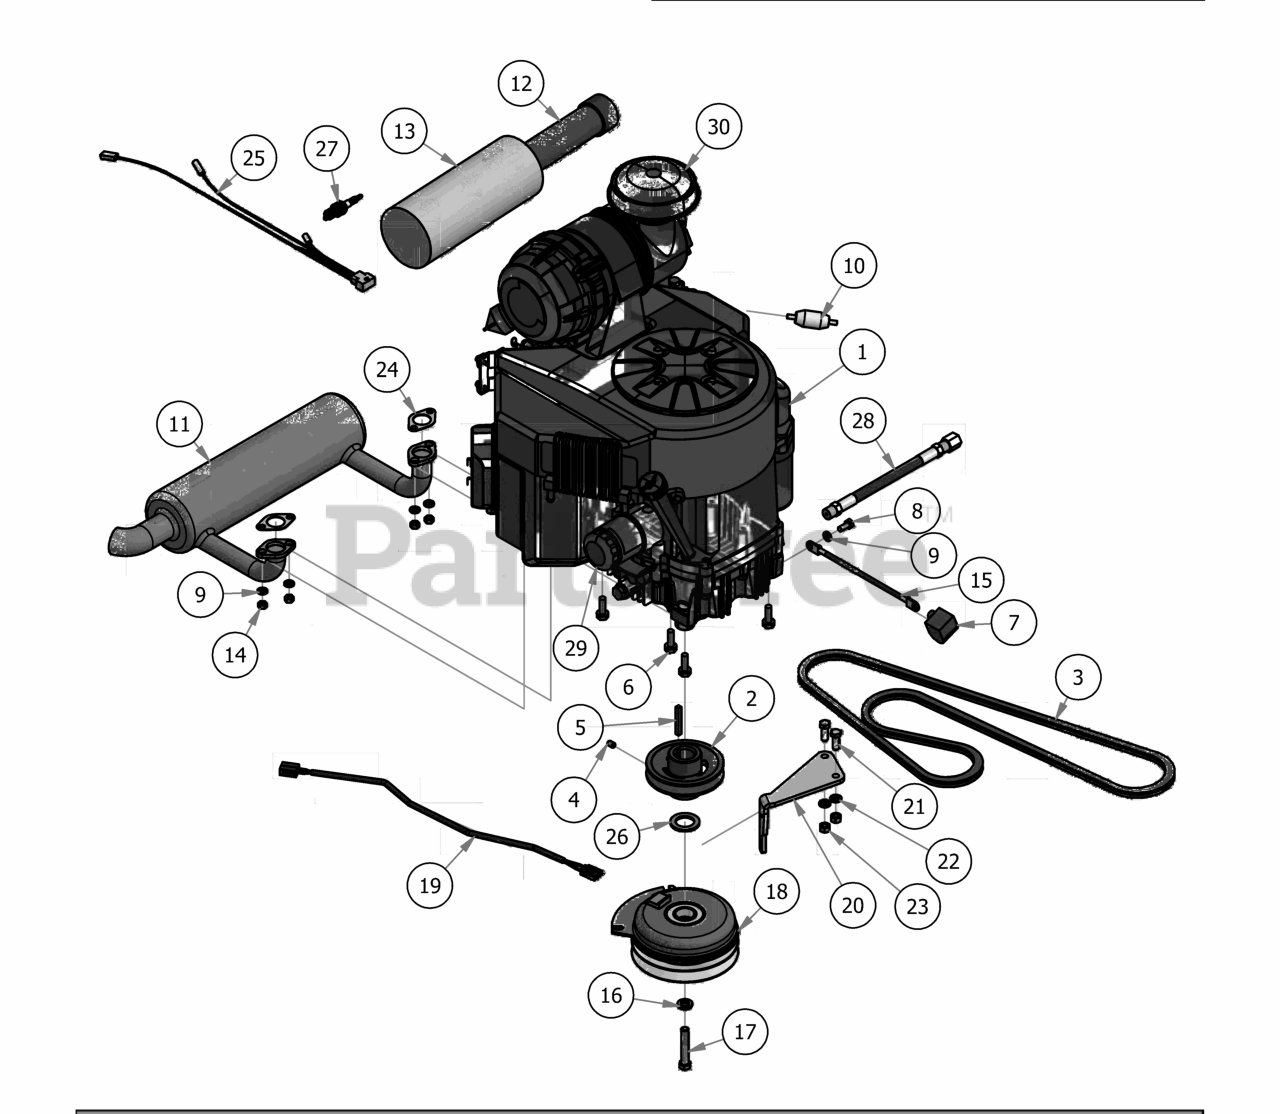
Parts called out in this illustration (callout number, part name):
1	FX-751-V Kawasaki
2	4 3/4 Motor Pulley
4	3/8" Set Screw
5	1/4 x 2 Square key Stock
6	3/8 x 1 1/8 bolt
7	Black Boot For Ground Cable
8	M8x1.20x20MM Hex head bolt
9	5/16" Lock Washer
10	Universal Inline Fuel Filter
11	Kawasaki Exhaust
12	Canister Air Filter- Inner
13	Canister Air Filter- Outer
14	M8-1.25 Zinc Nut
15	Ground Cable
16	7/16" Lock Washer
17	7/16" x 2 1/2" Hex Bolt
18	Clutch Assembly
19	Clutch Pigtail
20	PTO Engager Holder
21	3/8" x 1" Hex Bolt
22	3/8" Lock Washer
23	3/8" Hex Nut
24	Exhaust Gasket
25	Harness Adaptor
26	1 1/8" Flat Spacer
27	Spark Plug - Kawasaki
28	Oil drain Hose
29	Kawsaki Oil Filter
30	Kawasaki Rain Cap
